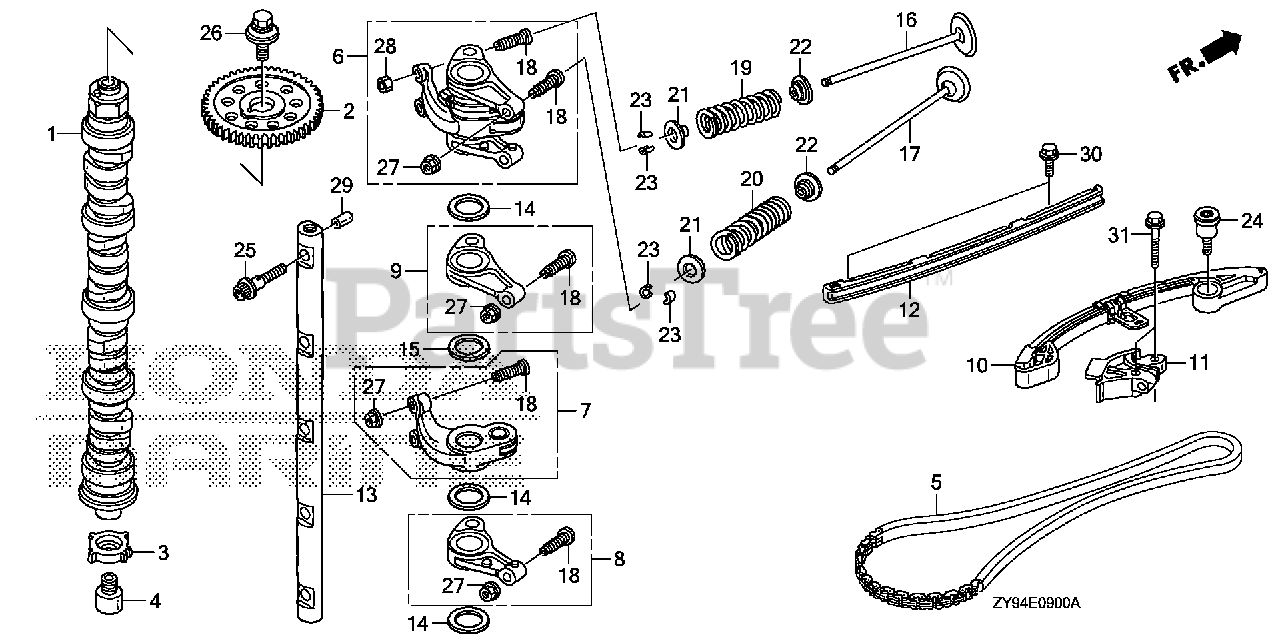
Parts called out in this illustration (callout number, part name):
2	SPROCKET, CAM CHAIN DRIVEN (46T)
3	PLATE, TDC PULSER
4	BOLT, TDC PULSER PLATE
5	CHAIN (132L)
7	ARM, IN. VALVE ROCKER
8	ARM A, EX. ROCKER
9	ARM B, EX. ROCKER
10	TENSIONER, CAM CHAIN
11	SLIDER, CAM CHAIN TENSIONER
12	GUIDE, CAM CHAIN
13	SHAFT, ROCKER ARM
14	WASHER, THRUST
15	WASHER, IN. WAVE
16	VALVE, IN.
17	VALVE, EX.
18	SCREW, TAPPET ADJUSTING
19	SPRING, IN. VALVE
20	SPRING, EX. VALVE
21	RETAINER, VALVE SPRING
22	SEAT, VALVE SPRING
23	COTTER, VALVE (FUJI VALVE)
24	BOLT, TENSIONER PIVOT
25	BOLT, ROCKER ARM SHAFT
26	BOLT-WASHER (10X30)
27	NUT, TAPPET ADJUSTING (TOKAI TRW)
29	PIN A, DOWEL (7X12)
30	BOLT, FLANGE (6X14)
31	BOLT, FLANGE (6X28)
